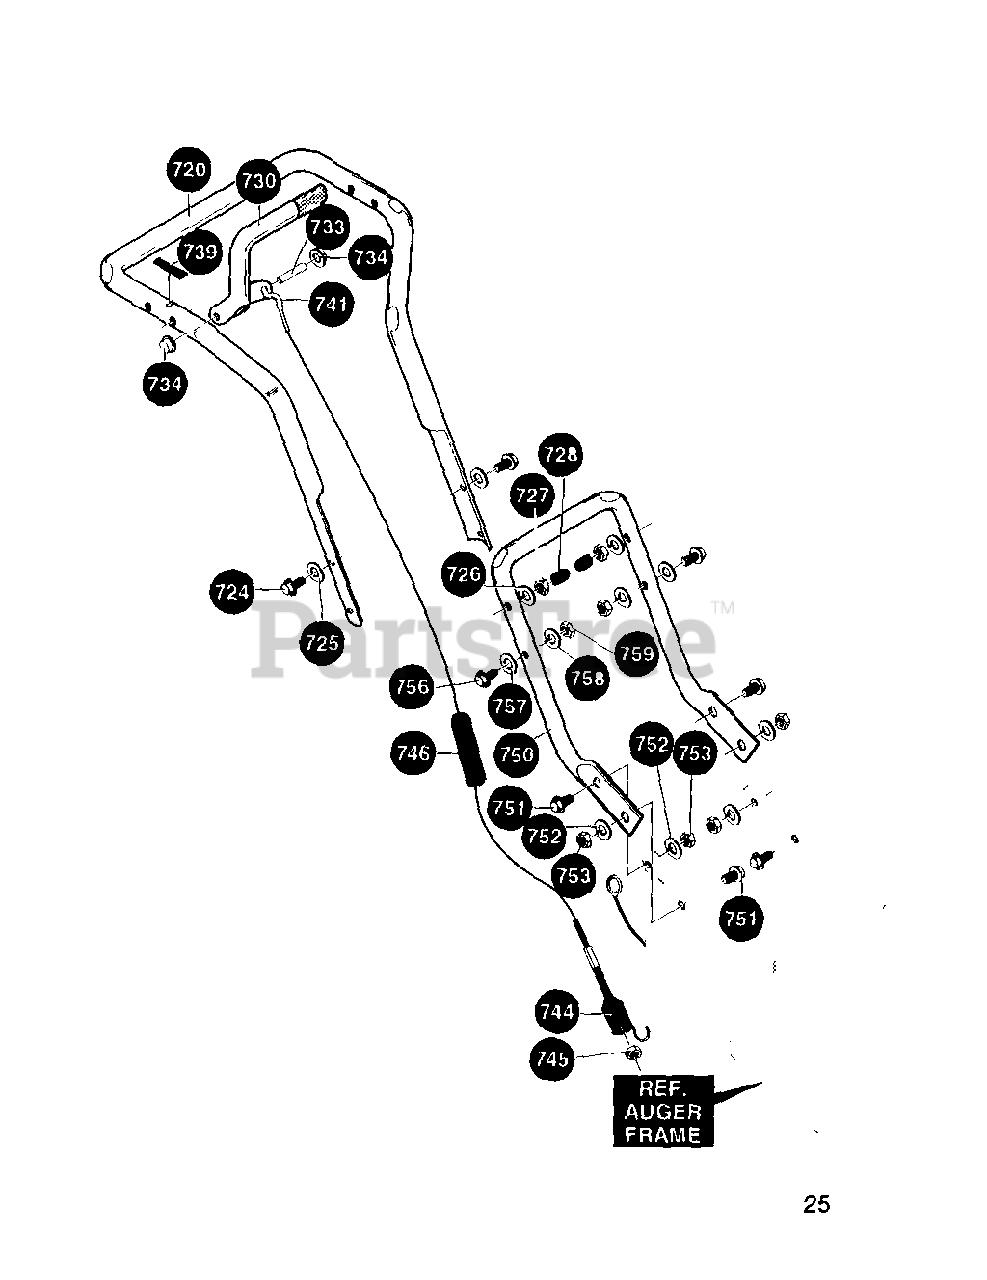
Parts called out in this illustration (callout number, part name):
720	Handle, Upper
724	Screw, 5/16-18 x 2.75
725	Flatwasher, .344 x .69 x .065
726	Washer, .328 x .60 x .09
727	Nut, 5/16-18
728	Stop, Red Plastic
730	Kit for Handle, Assy RH
733	Pin, Pivot
734	Nut, Push on Cap
739	Bumper, Rect
741	Cable, Clutch
744	Spring, Auger Clutch
745	Nut, 1/4-20
746	Boot, Clutch Spring
750	Handle, Lower
751	Screw, 5/16-18 x 1.00
752	Washer, .328 x .60 x .09
753	Nut, 5/16-18 Reghex
756	Screw, 5/16-18 x 2.00
757	Flatwasher, .344 x .69 x .065
758	Washer, .328 x .60 x .09
759	Nut, 5/16-18 Reghex
